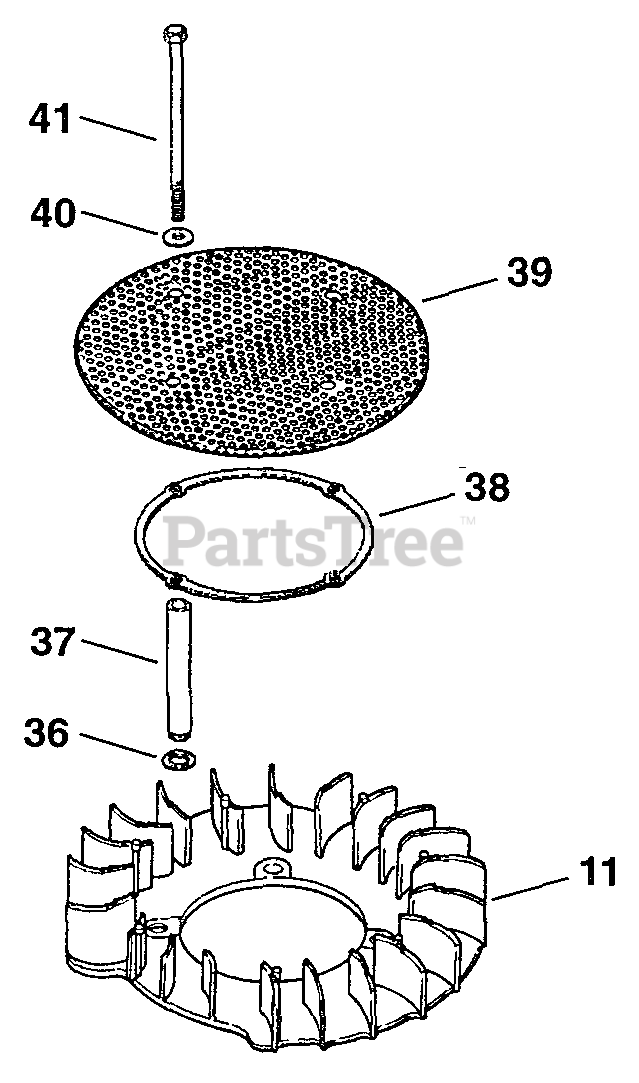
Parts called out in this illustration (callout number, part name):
37	Spacer, Grass Screen
39	Screen, Grass
40	Washer, Plain
